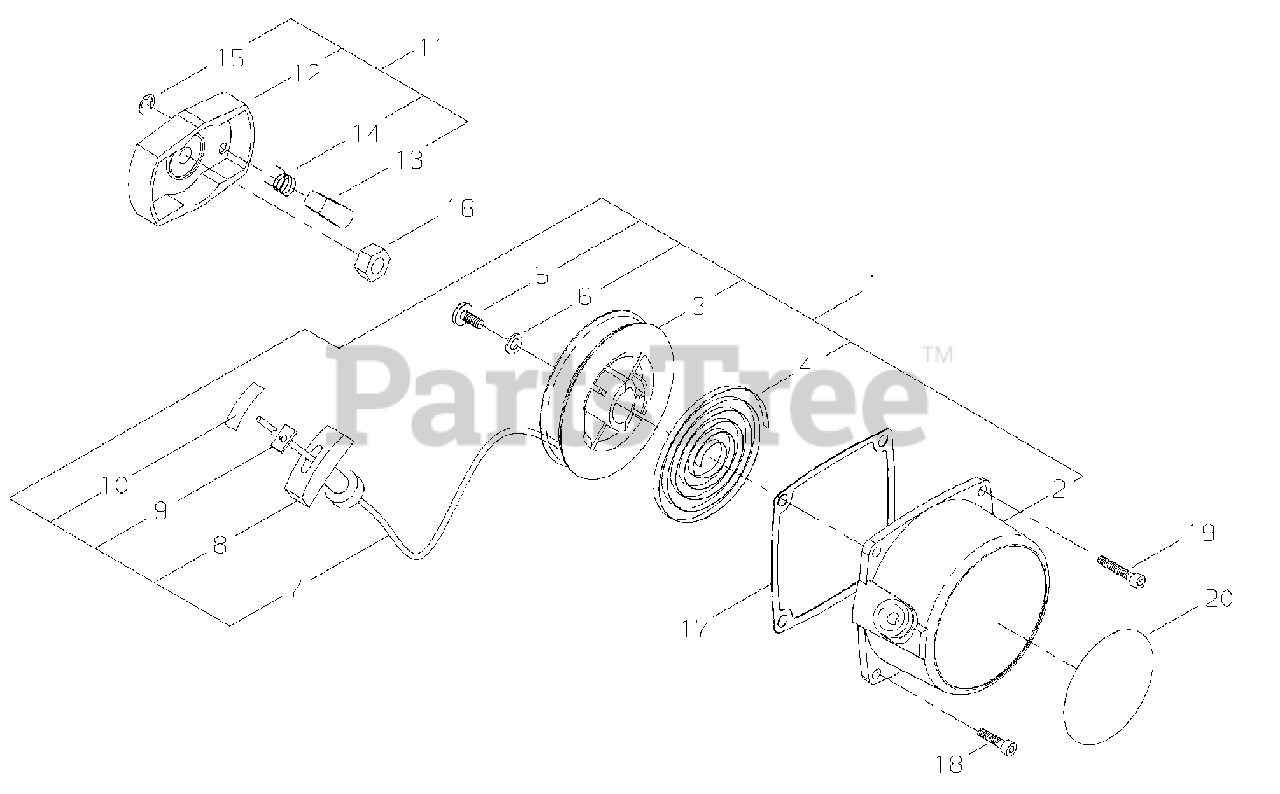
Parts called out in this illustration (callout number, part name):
1	STARTER ASSY
2	CASE, STARTER
3	REEL, ROPE
4	SPRING
5	SCREW
6	WASHER
7	ROPE
8	GRIP, STARTER
9	RETAINER, ROPE
10	TAPE
11	STARTER PAWL ASSY
12	REEL, ROPE
13	PAWL, STARTER
14	SPRING, RETURN
15	RING, RETAINING
16	NUT - 8
17	GASKET
18	SCREW - 4X16
19	SCREW - 4X20
20	LABEL - MODEL
